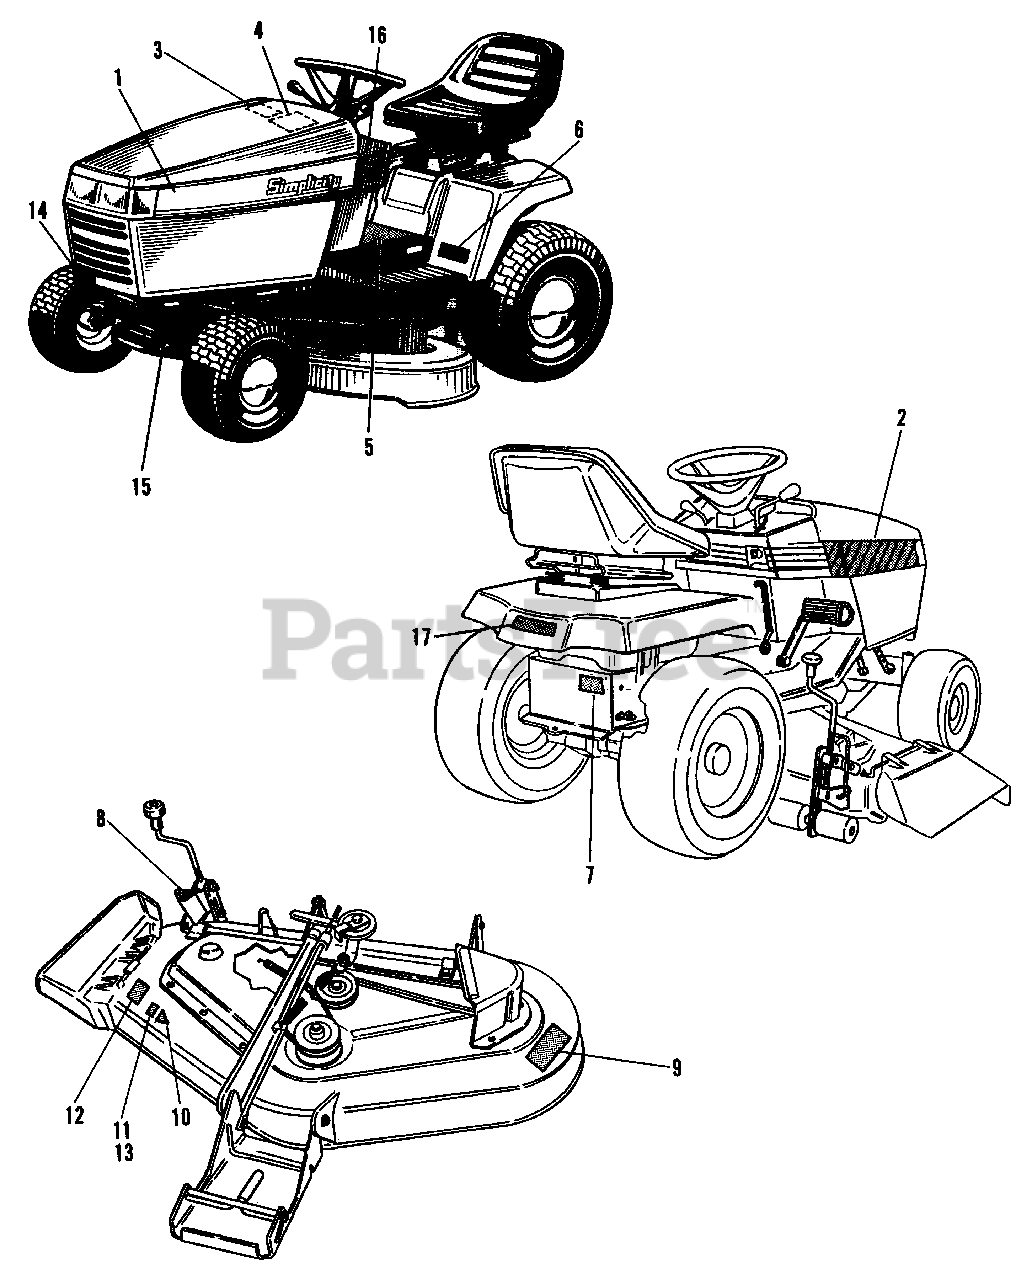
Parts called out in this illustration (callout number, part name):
1	DECAL, Hood, L.H.
2	DECAL, Hood, R.H.
3	DECAL, Paint
4	DECAL, Belt, Blade
5	DECAL, Operating Inst.
6	DECAL, 12.5 LTH
6	DECAL, 12.5 LTG
6	DECAL, 16 LTH
7	DECAL, Push Valve (Hydrostatic Units only)
8	DECAL, Mower Height
9	DECAL, Danger (Hand Under Deck)
10	DECAL, OPEI
11	DECAL, Cutting Width, 38"
13	DECAL, Cutting Width, 44"
14	DECAL, Grille, Hot
15	I.D. PLATE
16	DECAL, Choke (Dash), 12.5 0nly
17	DECAL, Logo
17	DECAL, Battery
